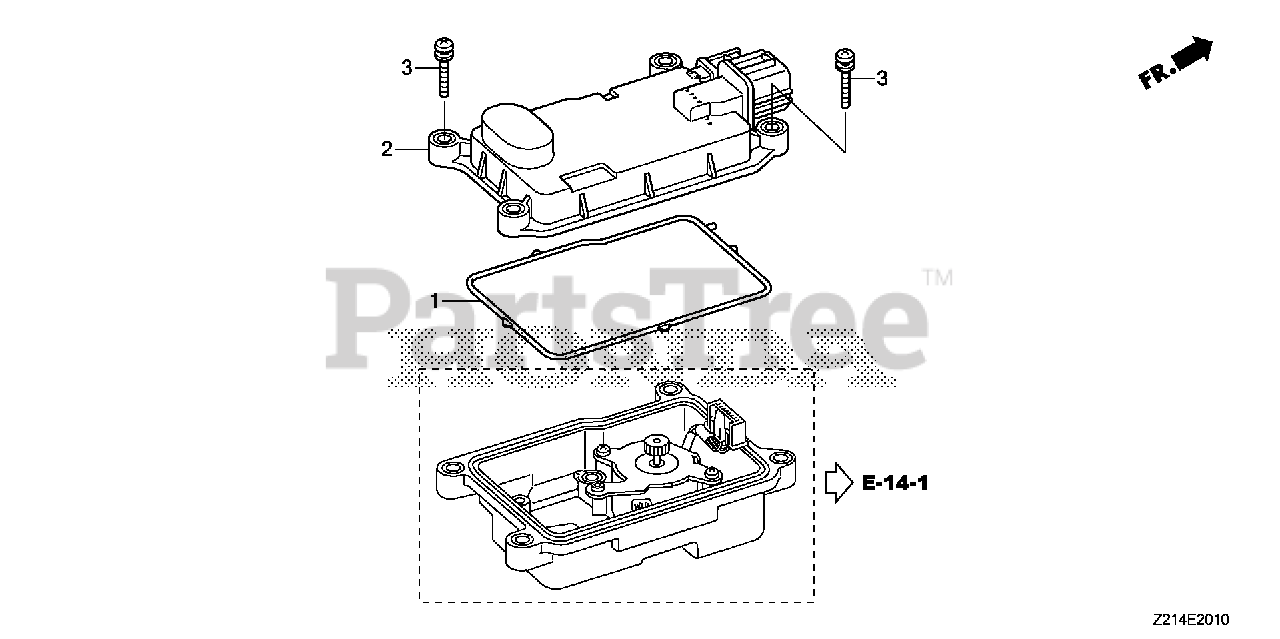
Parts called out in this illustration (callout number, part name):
1	SEAL, ELECTRONIC CONTROL UNIT COVER
2	CONTROL UNIT, ELECTRONIC
3	SCREW-WASHER (4X20)
